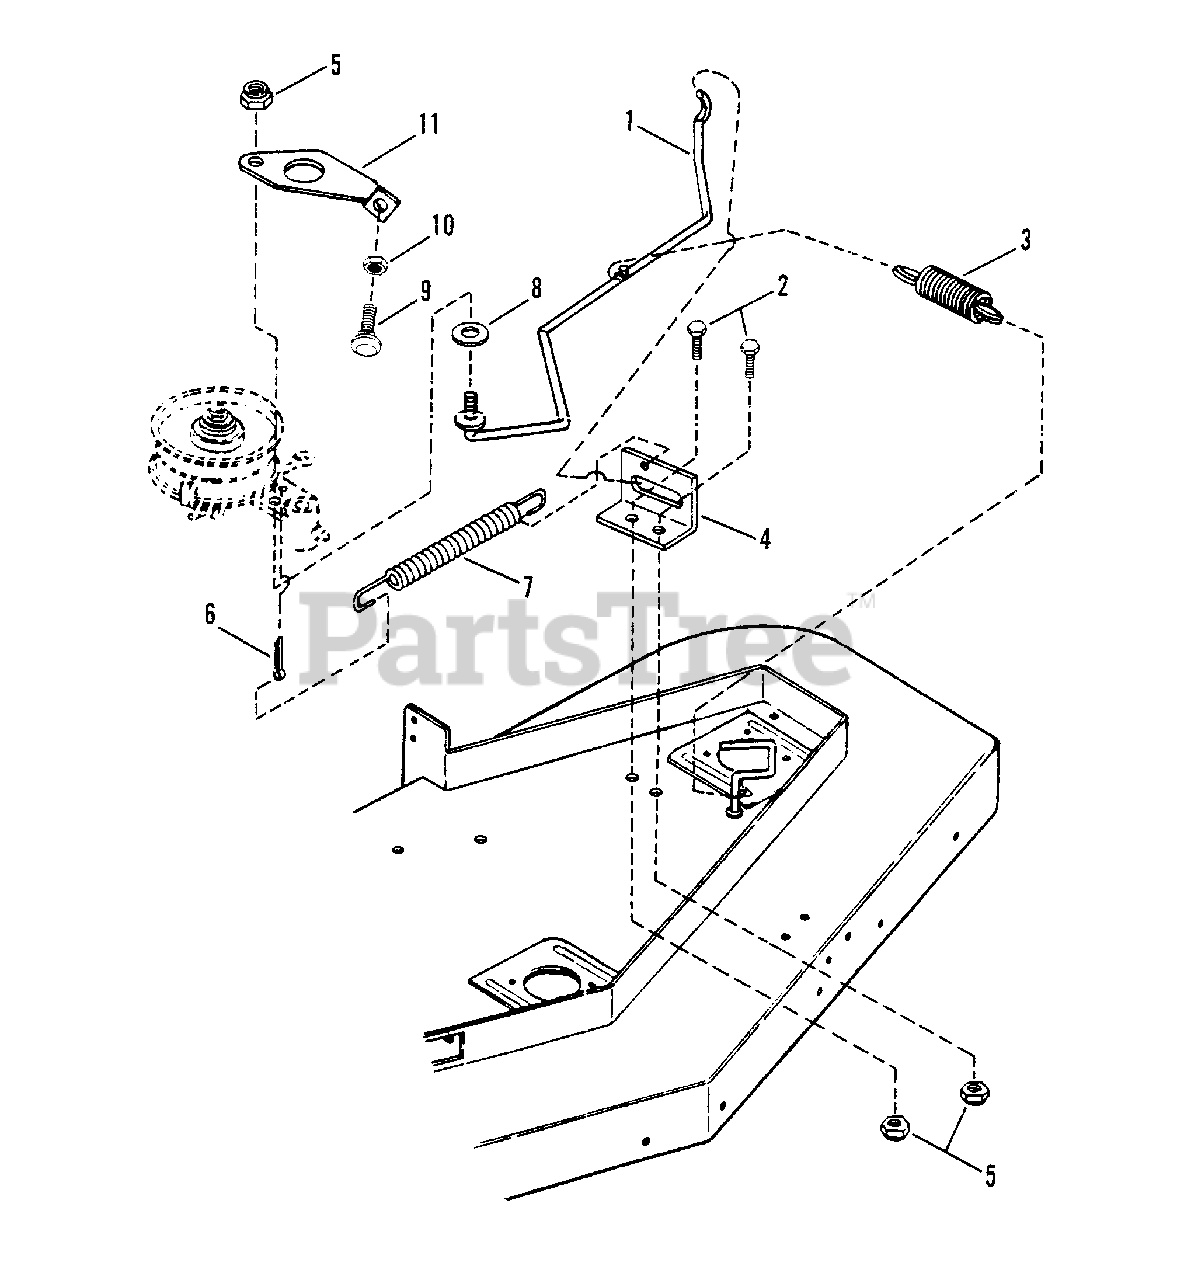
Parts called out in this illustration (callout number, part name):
1	GUIDE, Brake Belt
2	SCREW, 3/8 - 16 x 3/4" HHC
3	SPRING, Traction
4	BRACKET, Brake Arm
5	NUT, 3/8 Nyloc
6	COTTER PIN, 3/16 x 3/4"
7	SPRING, Idler Return
8	WASHER, 3/8 Wave
9	BOLT, 5/16 - 18 x 1 3/4 Carriage
10	NUT, 5/16-18 Jam
11	ARM, Brake, 48"
